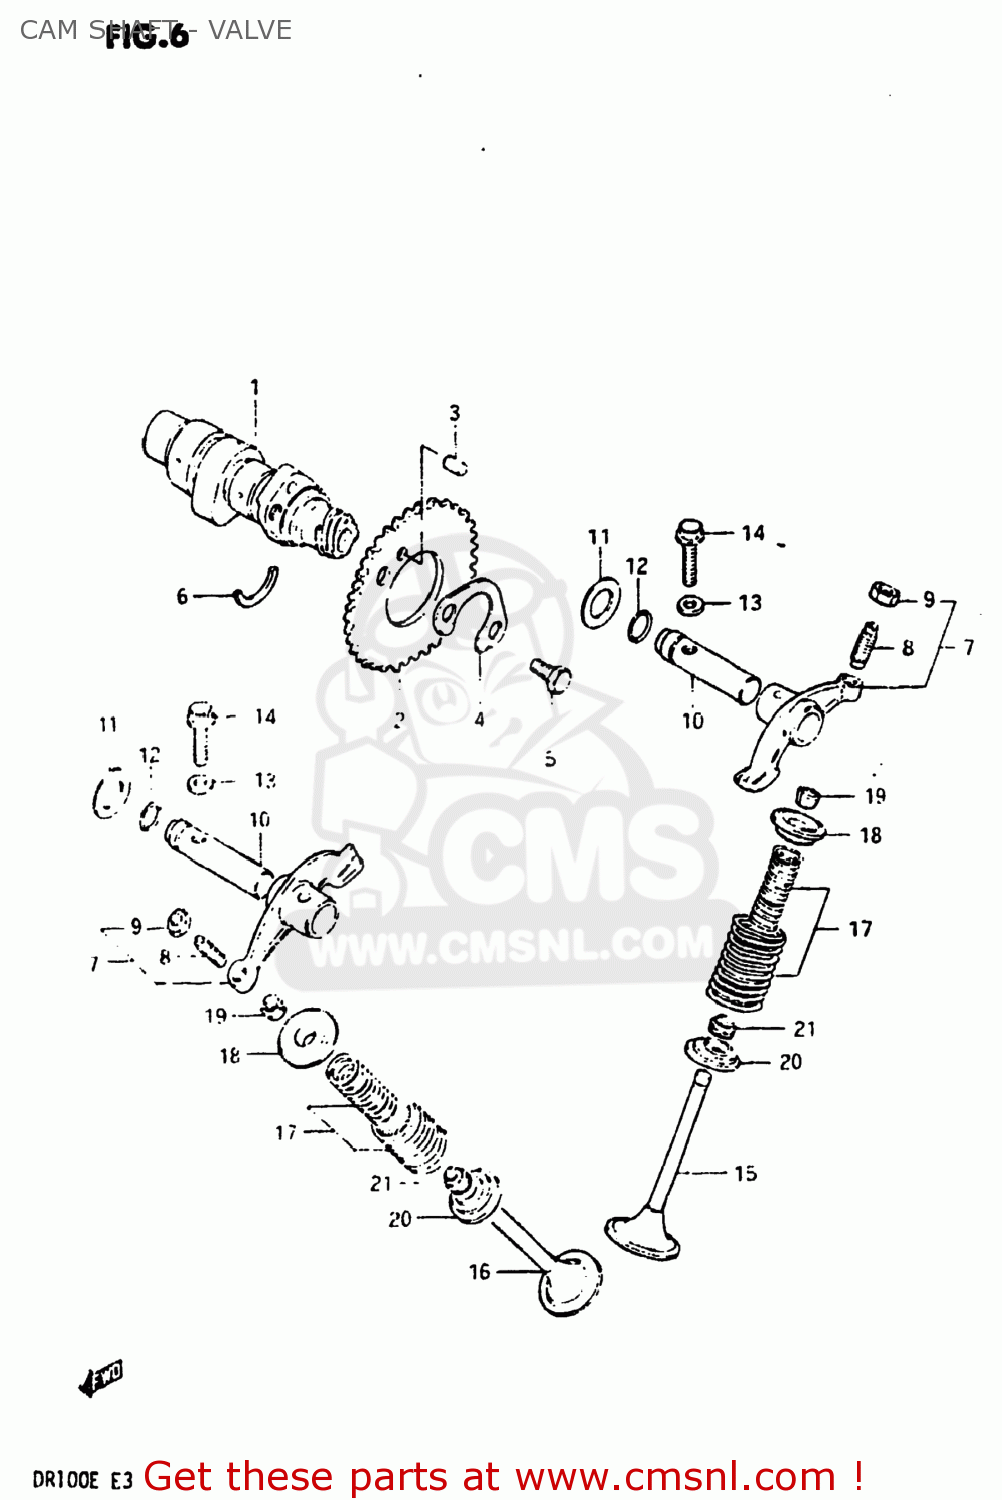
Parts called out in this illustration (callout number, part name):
1	CAMSHAFT
2	SPROCKET,CAMSHAFT
3	PIN(5X8)
4	WASHER,SPROCKET
5	BOLT(6X10.5)
6	C RING
7	ARM,VALVE ROCKER
8	SCREW,TAPPET ADJUSTING
9	NUT,ADJUSTING SCREW
10	SHAFT,VALVE ROCKET
11	WASHER
12	O-RING
13	WASHER
14	BOLT
15	VALVE,INTAKE
16	VALVE,EXHAUST
17	SPRING SET,VALVE
18	RETAINER,VALVE SPRING
19	COTTER VALVE
20	SEAT,VALVE SPRING
21	OIL SEAL
